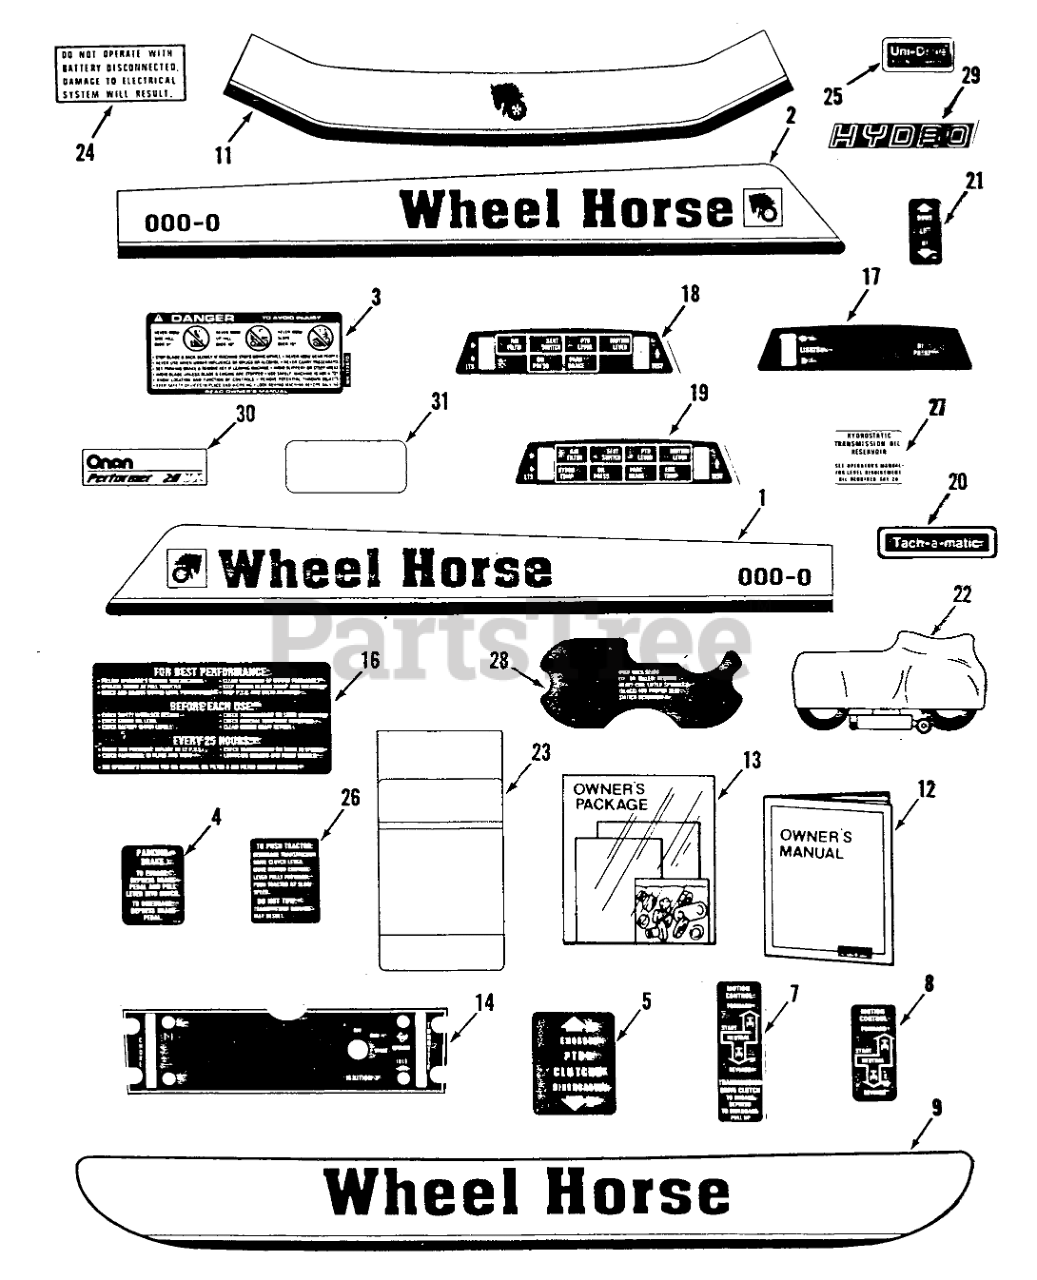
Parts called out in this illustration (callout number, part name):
1	DECAL-HOOD 518-H R H
2	DECAL-HOOD 518-H L H
3	DECAL-DANGER
4	DECAL-PARKING, BRAKE
5	DECAL PTO CLUTCH
7	DECAL-MOTION CONTROL
9	Decal-Rear Fender
11	DECAL-FRONT HOOD
14	Decal-Front Panel (31-16OE01, 31-18OE01, 31-20OE01 & C1-20OE10 VINs only)
16	DECAL-REAR HOOD
18	DECAL-INDICATOR LTS
20	Decal-Tach-a-matic
21	DECAL-LIFT
22	Vinyl Tractor Cover
23	Decal-Maintenance
24	DECAL ELECT SYSTEM
25	Decal-Unidrive
26	DECAL-TO PUSH TRACT
27	DECAL-TRANS OIL
28	DECAL-SEAT LIFTER
29	DECAL-HYDRO
30	Decal-Performer 16 HP (vendor #98-5640-02)
31	DECAL-OVERLAY
